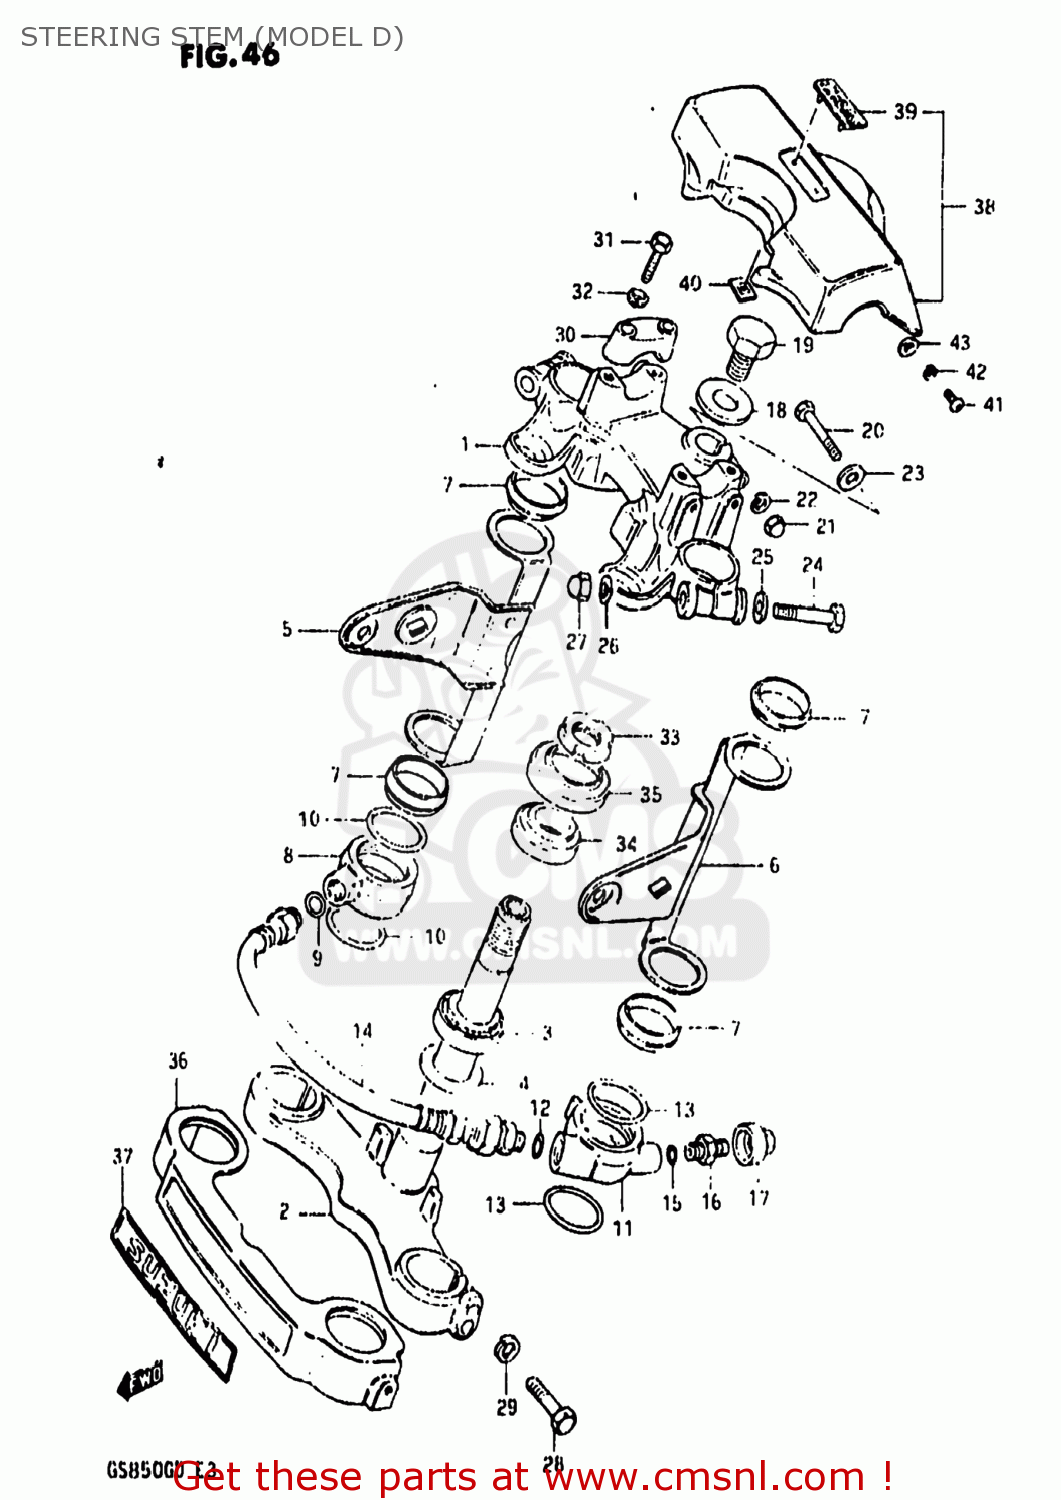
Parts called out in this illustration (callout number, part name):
1	HEAD,STEERING STEM
2	STEM,STEERING
3	BEARING
4	WASHER,THRUST
5	BRACKET,HEADLAMP,RIGHT
6	BRACKET,HEADLAMP,LEFT
7	CUSHION,HEADLAMP BRACKET
8	JOINT,AIR,RIGHT
9	O-RING
10	O RING
11	JOINT,AIR,LEFT
12	O-RING
13	O RING
14	HOSE
15	O-RING
16	VALVE,FRONT FORK AIR
17	CAP,VALVE
18	WASHER,STEERING STEM
19	NUT,STEM HEAD
20	BOLT 8X50
21	NUT
22	LOCK WASHER
23	WASHER
24	BOLT 10X55
25	WASHER
26	LOCK WASHER
27	NUT, LOWER LH
28	BOLT
29	LOCK WASHER
30	HOLDER,HANDLE(BLACK)
31	BOLT
32	LOCK WASHER
33	NUT,STEERING STEM
34	TAPER,ROLLER BEARING
35	DUST SEAL,STEERING UPR
36	COVER,FRONT FORK
37	EMBLEM,FRONT FORK COVER
38	PAD,HANDLEBAR
39	EMBLEM,HANDLE COVER PAD
40	NUT
41	SCREW
42	LOCK WASHER
43	WASHER
